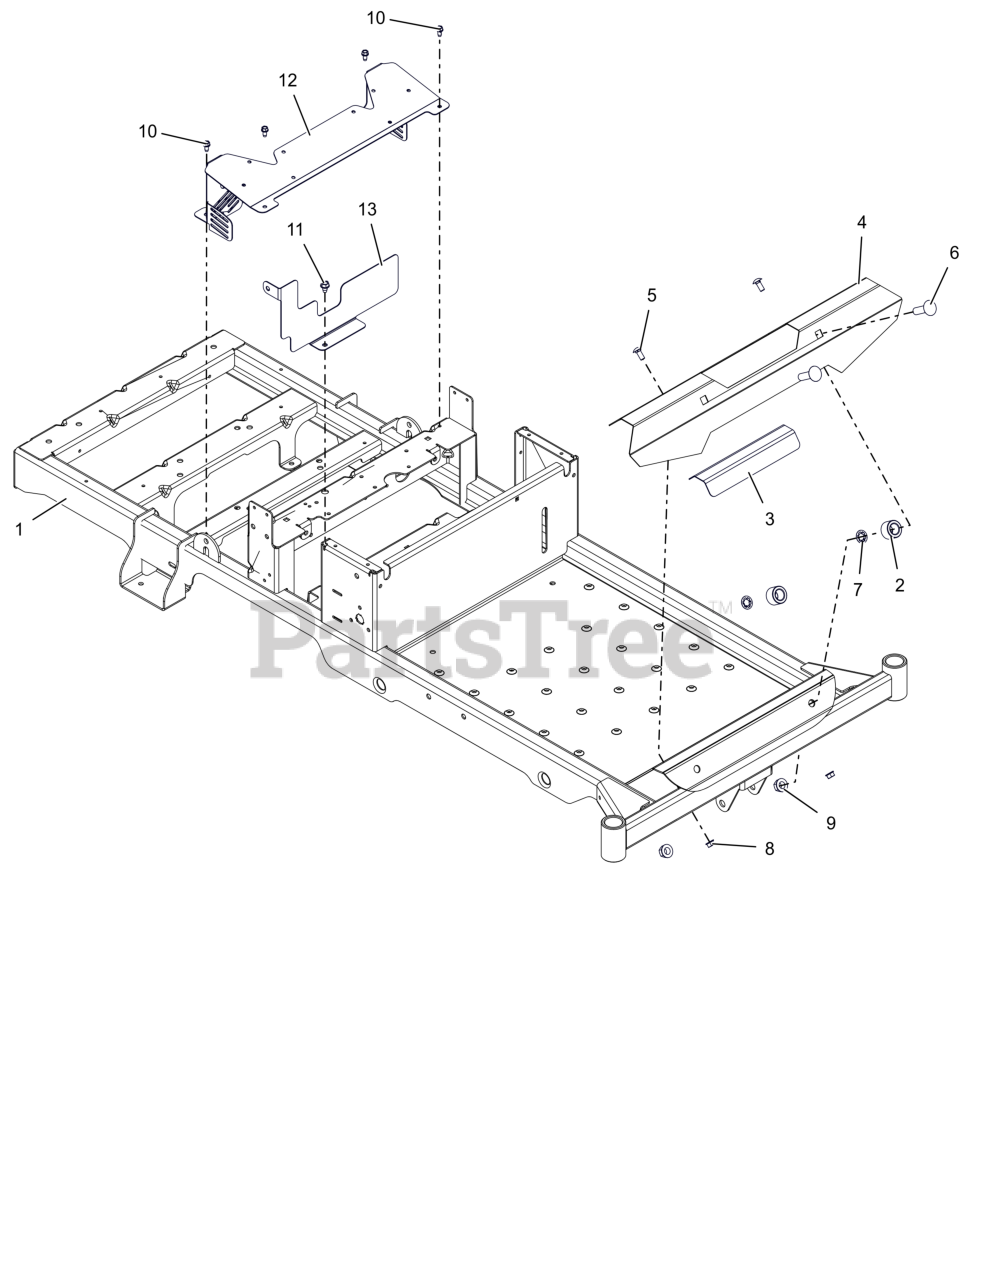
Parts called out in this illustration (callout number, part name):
1	KIT- EDGE FRAME W/DECALS
2	TUBE, UPPER CONTROL PIVOT
3	GRIP, STEP
4	FOOTREST, (ORANGE)
5	BLT, RHSSN.31-18X.750 G5 ZCC
6	BLT,RHSN .50-13X1.75 G5 ZCC
7	NUT-PUSH, .50
8	NUT,LK-CTR-FLG .31-18 GF ZCC
9	NUT-LK-CTR-FLG .500-13 GG ZCC
10	SCR-TAP .25-20X.50 HWH ZCC
11	SCR,TAP .312-18X.50 HWH TR ZCC
12	PLATE, FAN GUARD,CE
13	MUFFLER, LONCIN 635CC
